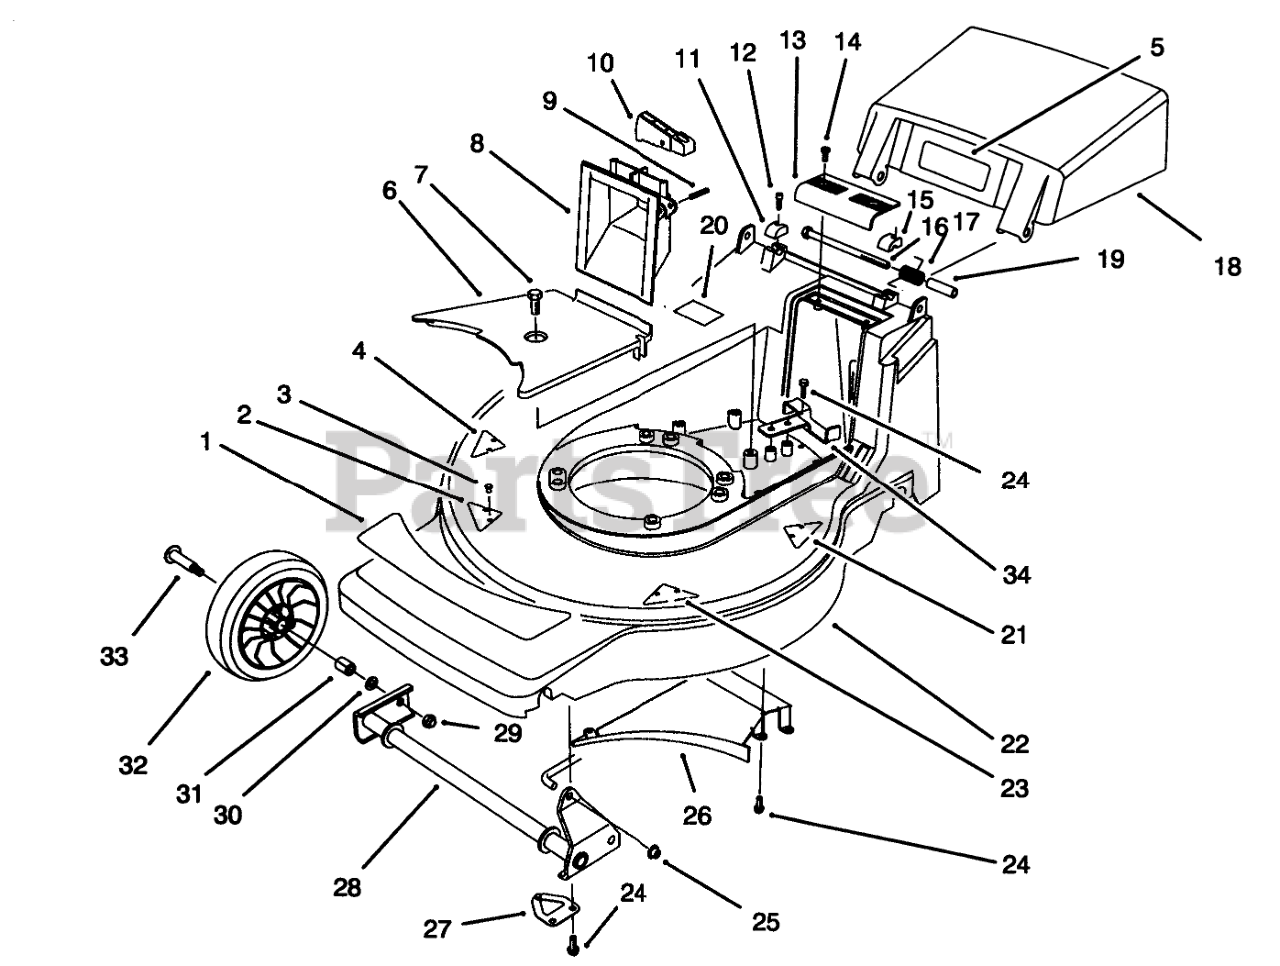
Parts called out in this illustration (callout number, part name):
1	DECAL - DECK
2	KICKER
3	SCREW-PPH
4	KICKER
5	DECAL-DANGER
6	BELT COVER
7	SCREW-HWHTF
8	GRIP - LOWER
9	PIN-SPIRAL
10	TRIGGER - HOC
11	CAP-HINGE BOLT, RH
12	SCREW-HSH
13	GRIP-UPPER
14	SCREW-PPH, PLASTITE
15	CAP-HINGE BOLT, LH
16	SCREW-HH
17	SPRING-DOOR
18	Door Discharge
19	SPACER-DOOR
20	Decal-Noise
21	KICKER
22	Housing-Deck (Incl. Ref. #2-5, 20, 21, & 23)
23	KICKER
24	SCREW-HWH
25	NUT-PUSH
26	Ramp-Discharge
27	SHAFT RETAINER ASM
28	FRONT PIVOT WA
29	NUT-HEX
30	WASHER
31	BUSHING
32	Wheel & Tire Assembly 7" (Incl. Ref. #31)
33	BOLT-WHEEL
34	REAR BELT GUIDE
